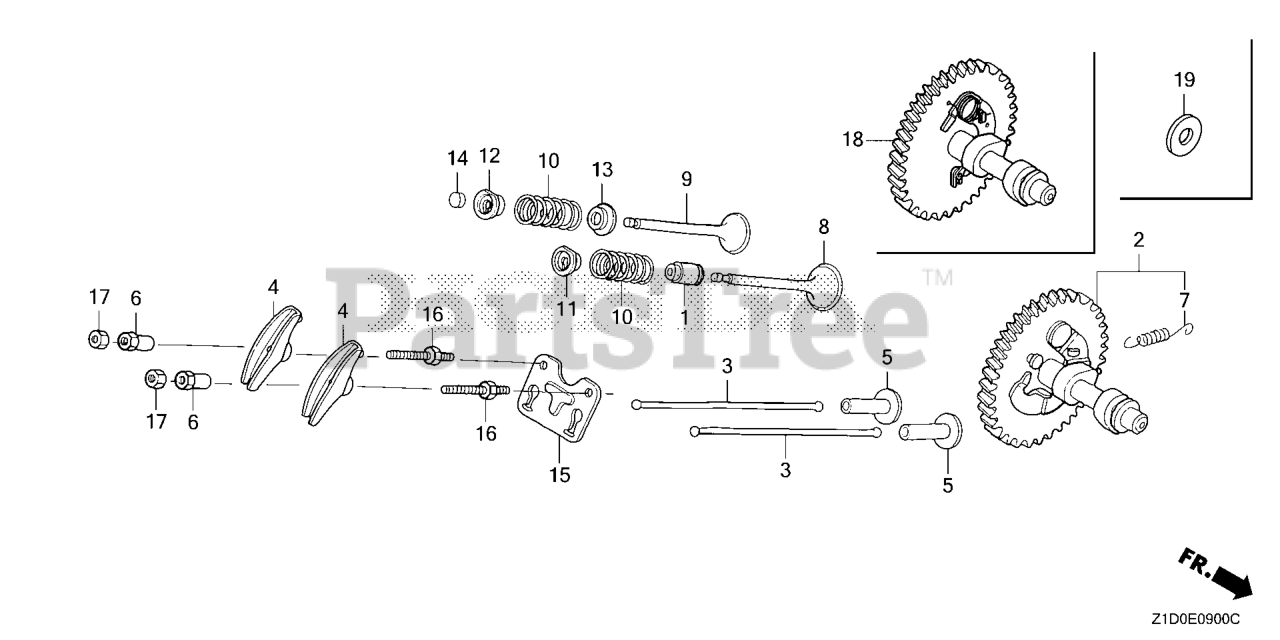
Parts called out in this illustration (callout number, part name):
1	SEAL, VALVE STEM
4	ARM, VALVE ROCKER
5	LIFTER, VALVE
6	PIVOT, ROCKER ARM
8	VALVE, IN.
9	VALVE, EX.
10	SPRING, VALVE
11	RETAINER, IN. VALVE SPRING (EXHAUST SIDE)
12	RETAINER, IN. VALVE SPRING (EXHAUST SIDE)
13	SEAT, VALVE SPRING
15	GUIDE, PUSH ROD
16	BOLT, PIVOT (8MM)
17	NUT, PIVOT ADJ.
18	CAMSHAFT ASSY.
